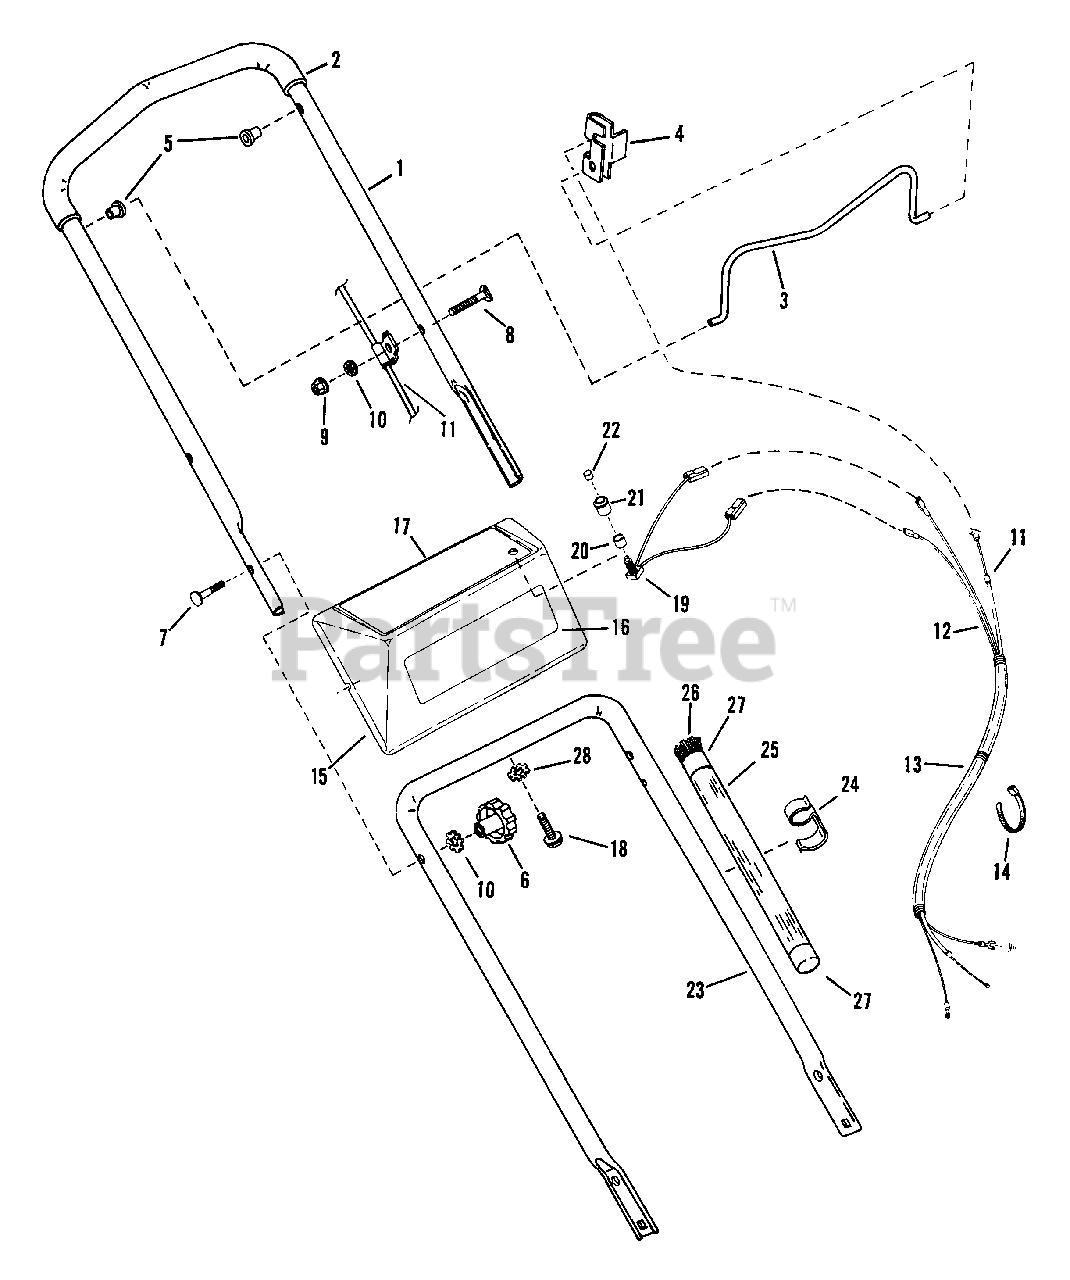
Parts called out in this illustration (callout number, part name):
1	HANDLE, Upper
2	GRIP, Foam
3	BAIL, Throttle
4	CLIP, Throttle
5	BUSHING, Bail
6	KNOB, 5/16-18 Plastic
7	BOLT, 5/16-18x2" Curved Head
8	BOLT, 1/4-20x1-1/2" Curved Head
9	NUT, 1/4-20 Hex Flange Lock
10	WASHER, 5/16 Int./Ext. Tooth Lock
11	ASSEMBLY, Throttle Cable
12	HARNESS, Wire
13	SHEATH, Harness
14	TIE, Cable
15	ASSEMBLY, Panel/Label
16	LABEL, Model
17	LABEL, Instruction
18	SCREW, 5/16-18x5/8" Self-Tapping
20	SPACER, Switch
21	BEZEL, Switch
22	CAP, Switch
23	HANDLE, Lower
24	CLIP, Wire
25	TUBE, Plastic
26	LINE, .130 DIA.
27	CAP, Tube
28	WASHER, 5/16 Int./Ext. Tooth Lock
